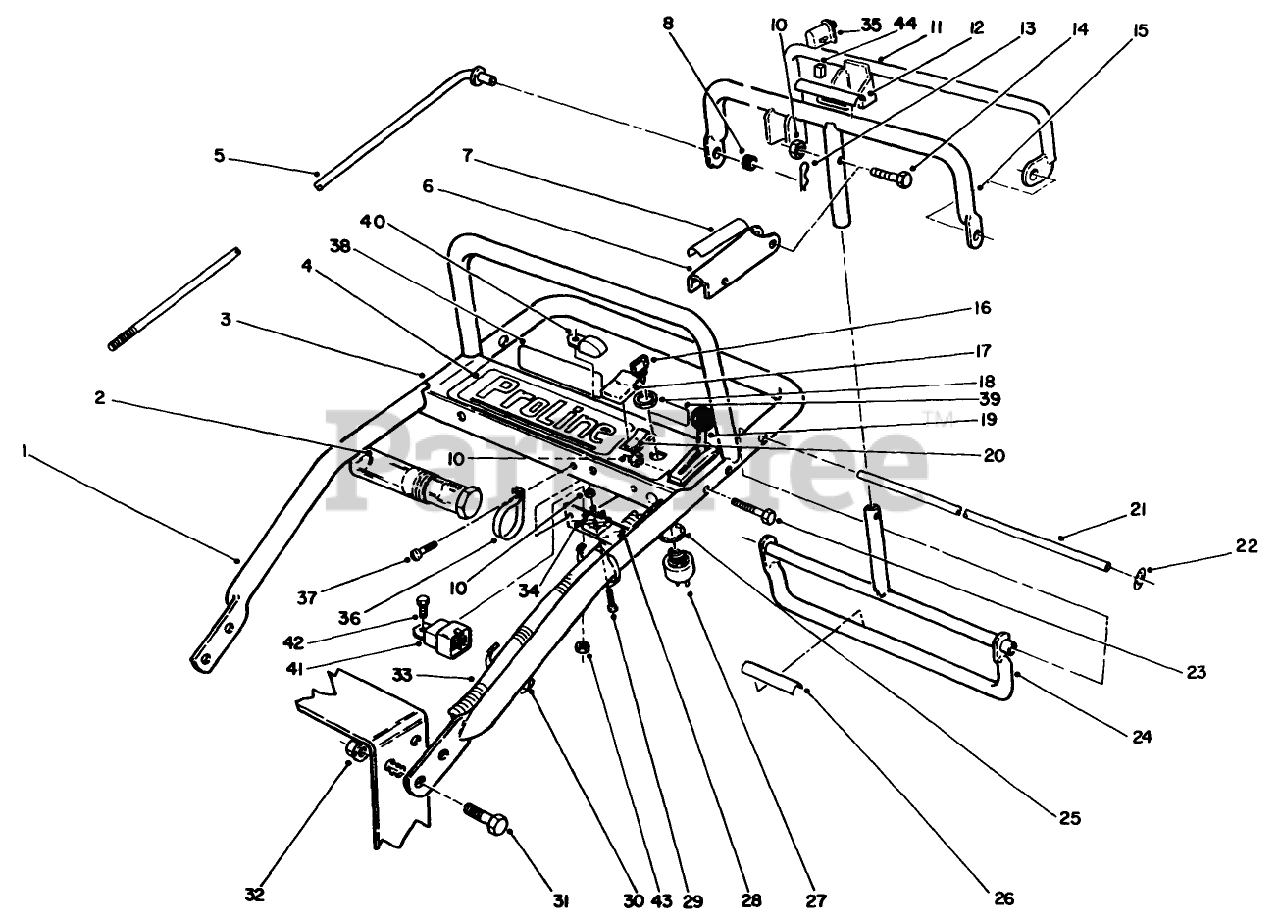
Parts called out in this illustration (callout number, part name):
2	TUBE-MANUAL
5	ROD-CONTROL
7	DECAL-LEVER, PARKING
8	GROMMET-RUBBER
10	NUT-LOCK, NI
12	DECAL
14	SCREW-SHH
16	KEY-IGNITION
17	BOOT-SWITCH
18	NUT-HH
19	CONTROL-THROTTLE
21	PIVOT ROD
22	NUT-PUSH-ON, CIRCULAR
23	SCREW-SHH
25	WASHER-LOCK
26	DECAL
27	SWITCH-ON / OFF
29	SCREW-HWH
30	TIE-CABLE
31	SCREW-HHF
32	NUT-HF
33	Wire Harness (Ref.)
34	RECTIFIER-BRIDGE
35	SWITCH-BAIL
36	CLAMP-R
37	SCREW-HWHTF
38	DECAL-INSTRUCTION
39	DECAL-INSTRUCTION, SAFETY
41	RELAY
42	SCREW-HH
43	NUT-LOCK, NI
44	CONNECTOR-BODY
